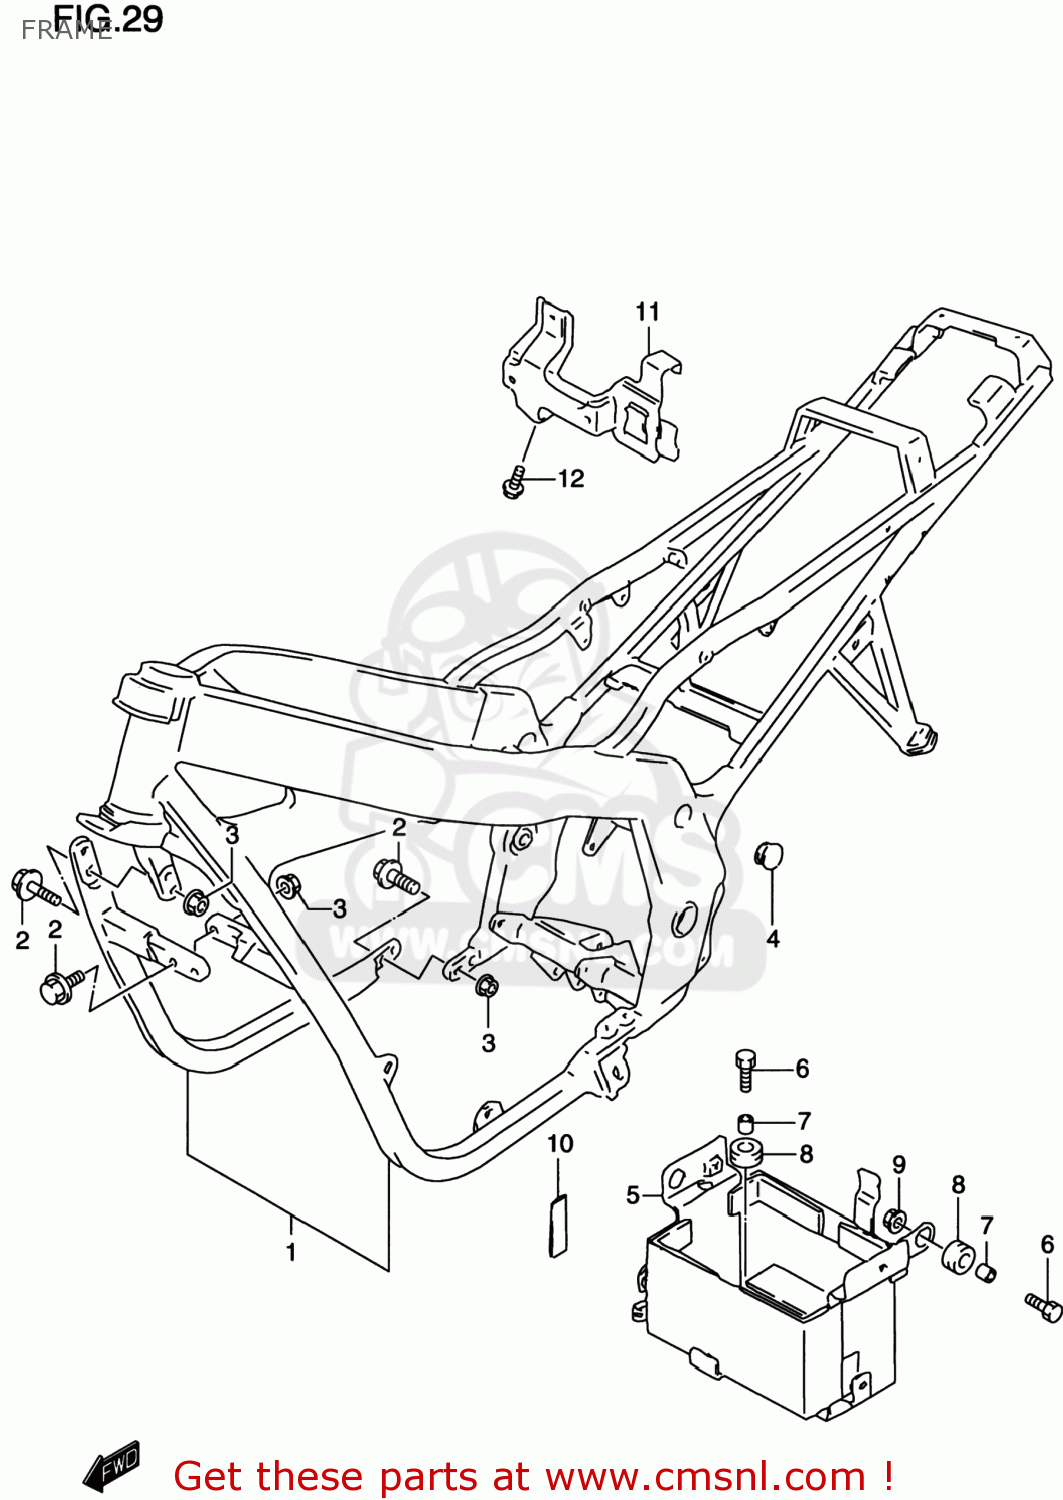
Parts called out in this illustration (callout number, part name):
1	FRAME SET
2	BOLT
3	NUT
4	CAP,BODY FRAME
5	HOLDER,BATTERY
6	BOLT(6X20)
7	SPACER(6.1X9X7.5)
8	CUSHION
9	NUT
10	CUSHION
11	HOLDER,ELECTRIC PARTS
12	BOLT
